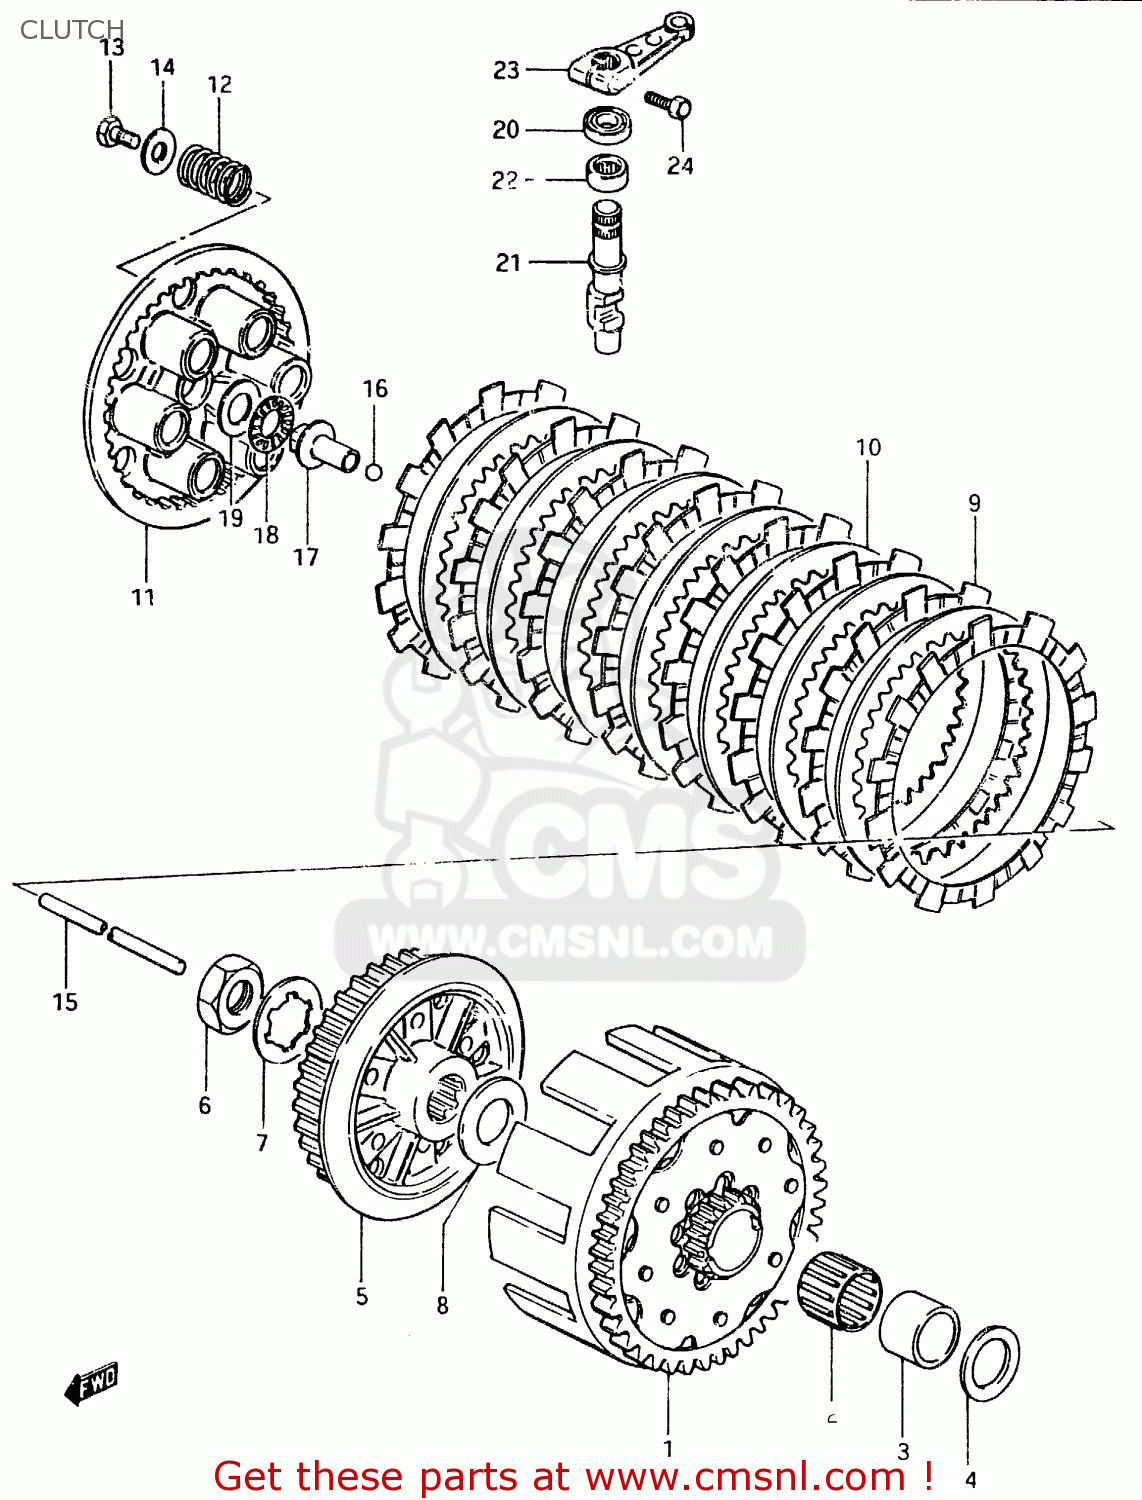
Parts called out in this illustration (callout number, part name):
1	GEAR ASSEMBLY,PRIMARY DRIVE
2	BEARING(28X33X27)
3	SPACER(22X28X27)
4	WASHER
5	HUB,CLUTCH SLEEVE
6	NUT
7	WASHER,LOCK
8	WASHER
9	PLATE,CLUTCH DRIVE (MCA)
10	PLATE,CLUTCH DRIVEN (NAS)
11	DISC,CLUTCH PRESSURE
12	SPRING
13	BOLT, UPPER
14	WASHER
15	ROD,CLUTCH PUSH
16	BALL
17	PIECE,CLUTCH PUSH
18	BEARING(15X28X2)
19	WASHER
20	SEAL,OIL(12X19X5)
21	SHAFT,CLUTCH RELEASE C
22	BEARING(12X19X12)
23	ARM,CLUTCH RELEASE
24	BOLT
